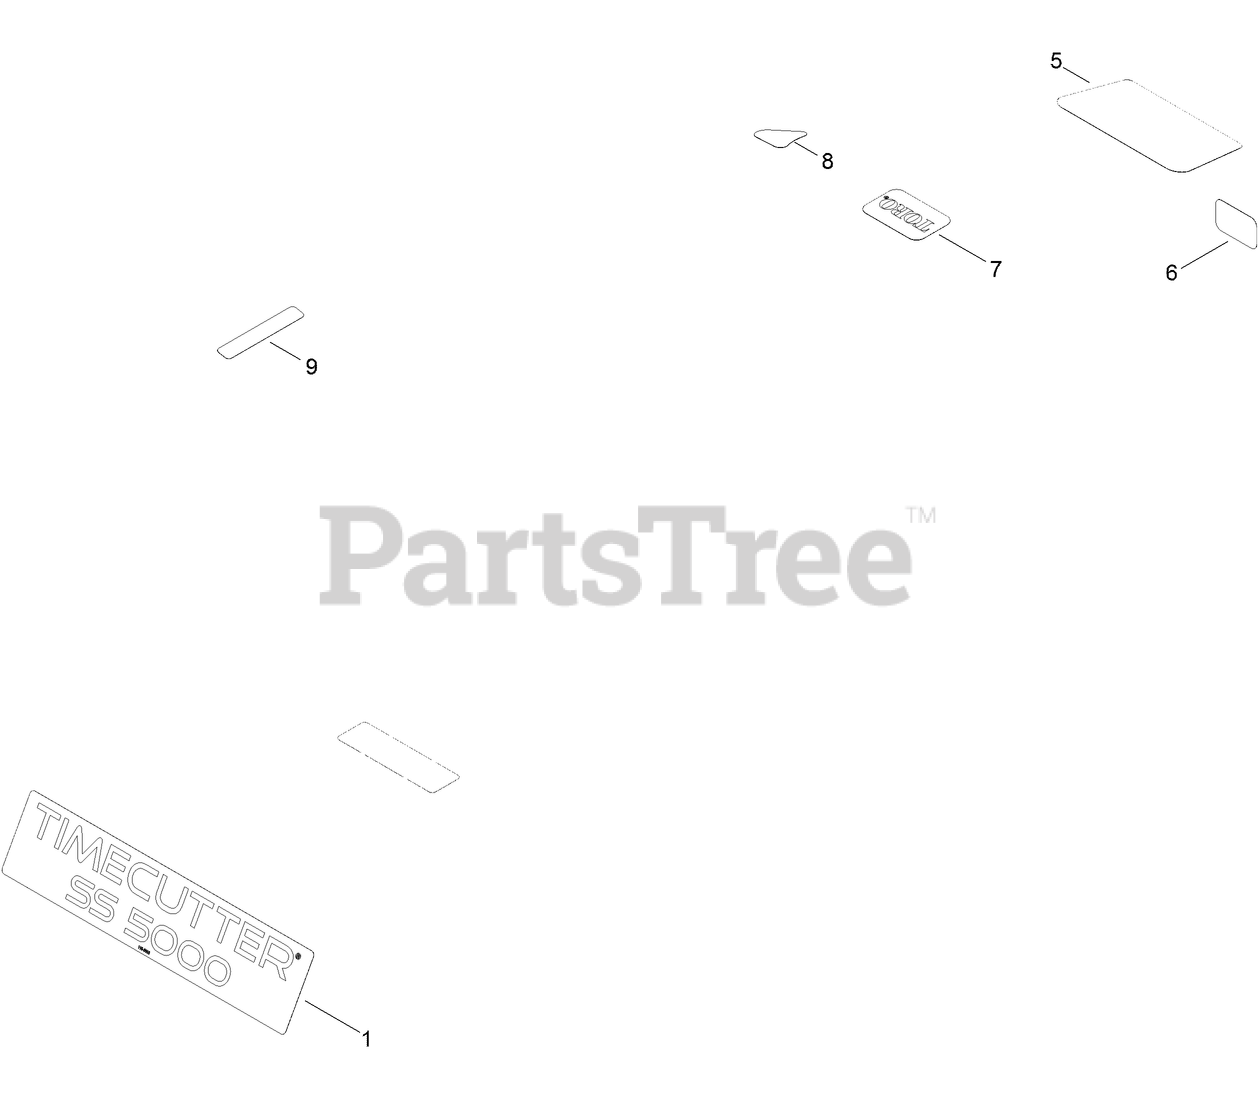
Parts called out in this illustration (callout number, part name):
1	DECAL-TIMECUTTER
5	DECAL-ENGINE
6	PLACARD-INTAKE
8	DECAL-DRAIN, OIL
9	DECAL-SHUTDOWN
